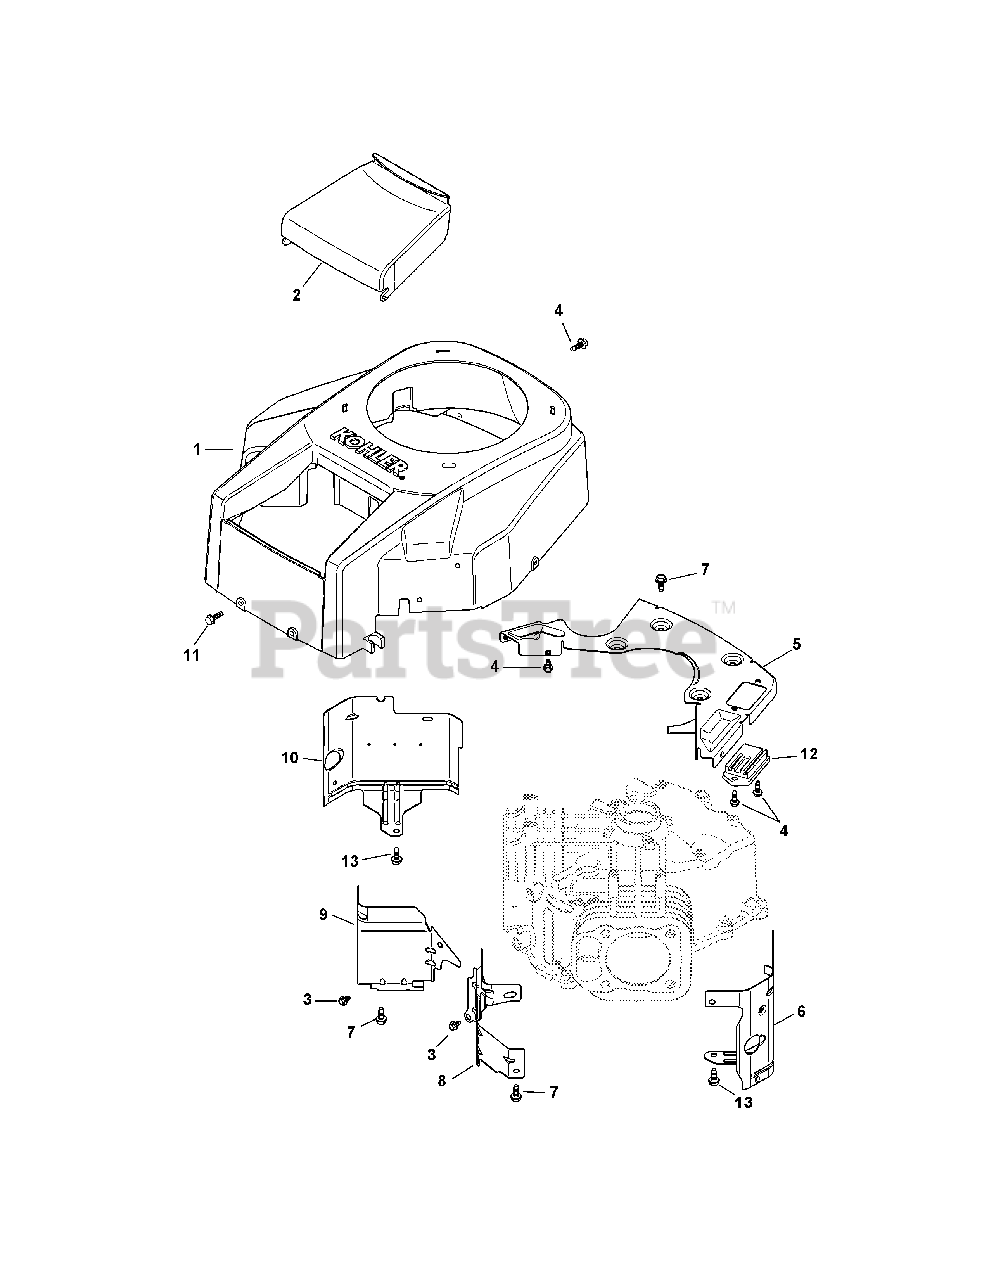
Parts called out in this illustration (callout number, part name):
1	Blower Housing Kit
2	Air Cleaner Cover
3	Flange Screw, M5 x .8 x 10
4	Flange Screw, M5 x .8 x 16
5	Backing Plate Kit
6	Cylinder Barrel Baffle, #2 Side
7	Flange Screw, M6 x 1.0 x 16
8	Valley Baffle, #2 Cylinder
9	Valley Baffle, #1 Cylinder
10	Cylinder Barrel Baffle, #1 Side
11	Screw, M6 x 1.7 x 18
12	Regulator/Rectifier
13	Flange Screw, M6 x 1.0 x 10
NS	Nameplate Service
